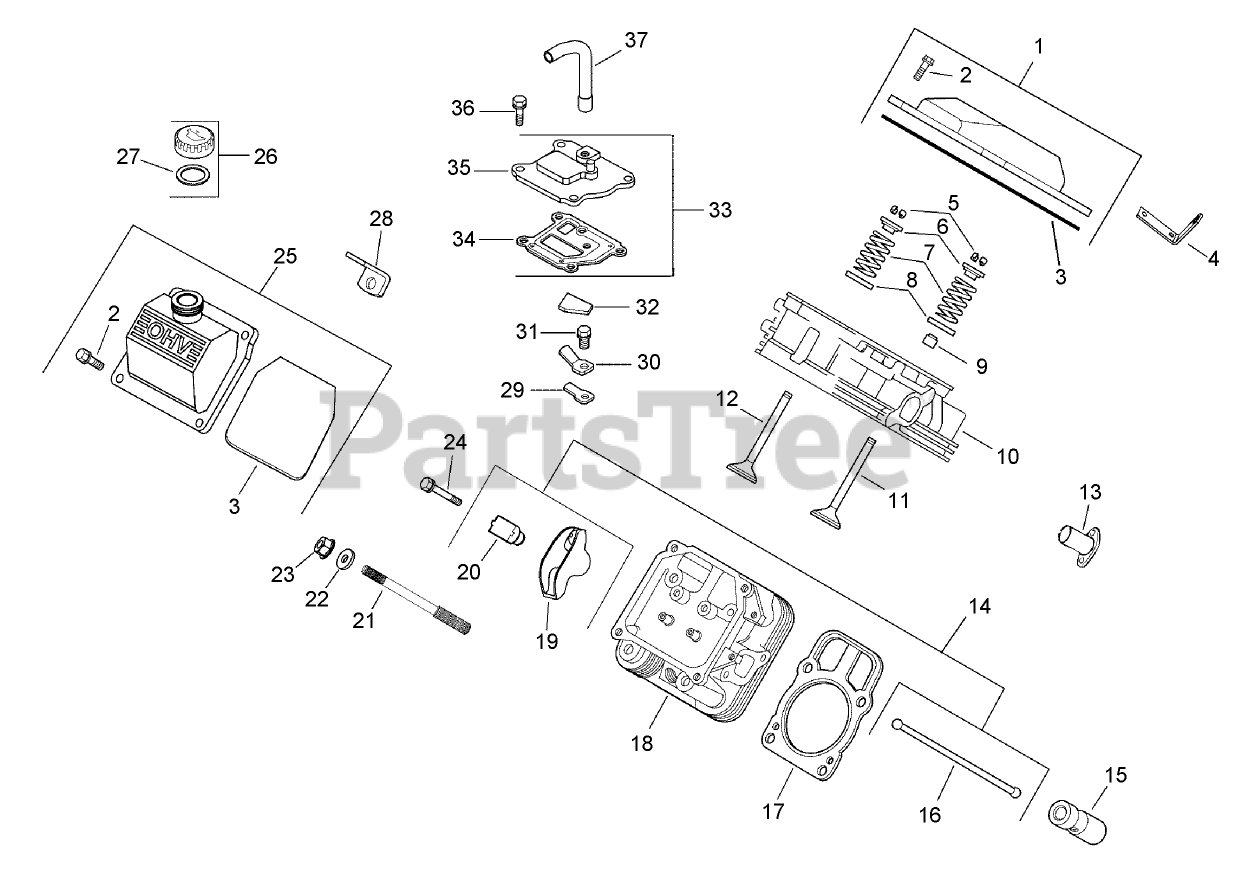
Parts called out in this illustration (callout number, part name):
1	Plain Valve Cover Kit (Includes 2,3)
2	SCREW-FLANGE (M6X1.0X30)
3	O-Ring
4	STRAP-LIFTING
5	RETAINER KIT
6	CAP-SPRING, VALVE
7	SPRING-VALVE
8	RETAINER-SPRING
9	SEAL-STEM, VALVE
10	CYLINDER HEAD ASM
11	VALVE-INTAKE (STD)
11	VALVE-INTAKE (.25)
12	VALVE-EXHAUST (STD)
12	VALVE-EXHAUST (.25)
13	Liner-Port, Exhaust
14	Valve Train Kit (Includes 16, 19, 20)
15	Lifter-Valve
16	ROD-PUSH
17	Cylinder Head Gasket Kit (Includes 22, 23)
18	CYLINDER HEAD ASM
19	ARM-ROCKER
20	Pivot-Arm, Rocker
21	STUD (M8X1.25xM10X1.5x105MM)
22	WASHER-FLAT (8.6 MM)
23	NUT-FLANGE (M8X1.25)
24	Screw
25	Oil Fill Valve Cover Kit (Includes 2, 3)
26	Oil Fill Cap Kit (Includes 27)
27	O-RING
28	Strap-Lifting
29	REED-BREATHER
30	RETAINER-REED
31	SCREW-HHFTF (M5X.80X10)
32	Filter-Breather
33	Breather Kit (Includes 34, 35)
34	GASKET-BREATHER
35	COVER-BREATHER
36	SCREW-HHFTF (M6X1.0X20)
37	Hose-Breather
